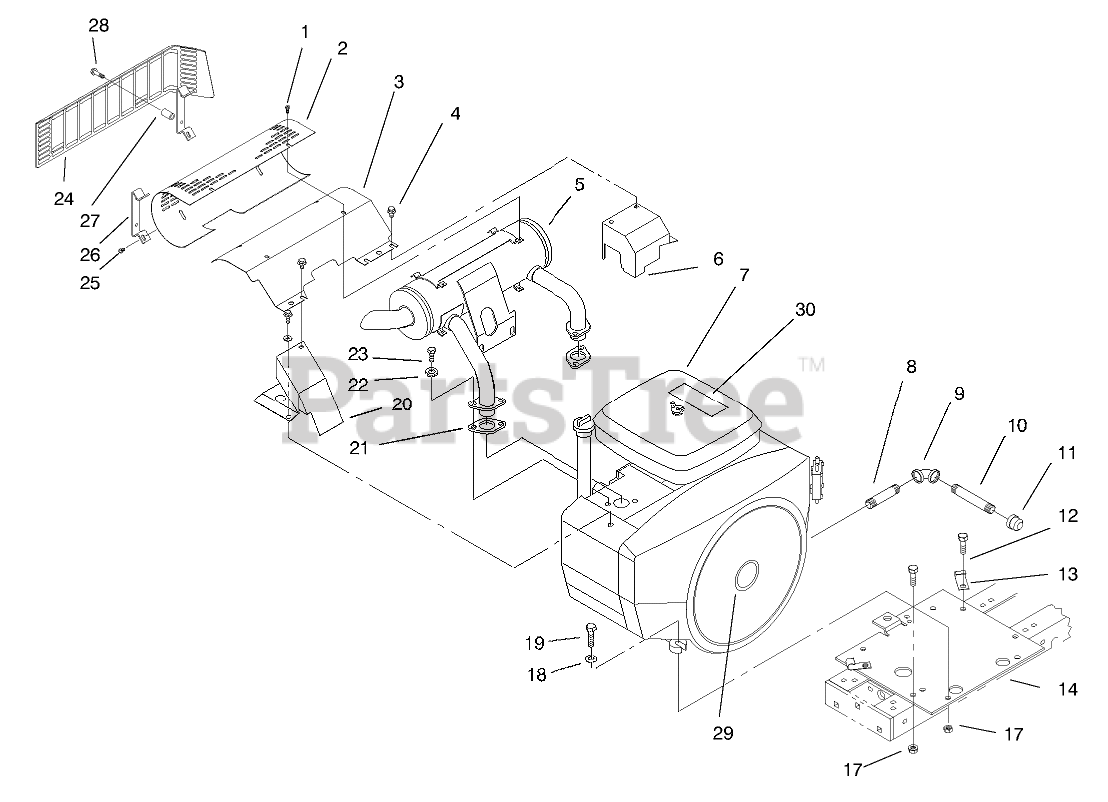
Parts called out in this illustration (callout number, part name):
1	SCW 10-24 STAINLESS
2	SHIELD - HEAT
3	Baffle-Deflector
4	SCREW-HWHTF
5	MUFFLER-EXHAUST
6	COVR-EXHAST (BLACK)
7	Engine-Onan
8	Pipe
9	ELBOW 3/8 90 DEG
10	PIPE-NIPPLE 3/8 X 4"
11	CAP-PIPE
12	SCREW-HH
13	CLIP
14	Plate-Engine
17	NUT-LOCK, NI
18	WASHER-FLAT
19	SCREW-HH
20	COVR-EXHAST (BLACK)
21	GASKET
22	WASHER-LOCK
23	SCREW-HH
24	SHIELD - HEAT (BLACK)
25	Screw-Phcr
26	Bar-Guard
27	SPACER
28	SCREW-HWH
29	NAME-PLATE TORO LOGO
30	DECAL-PWR PLUS 16 PL
